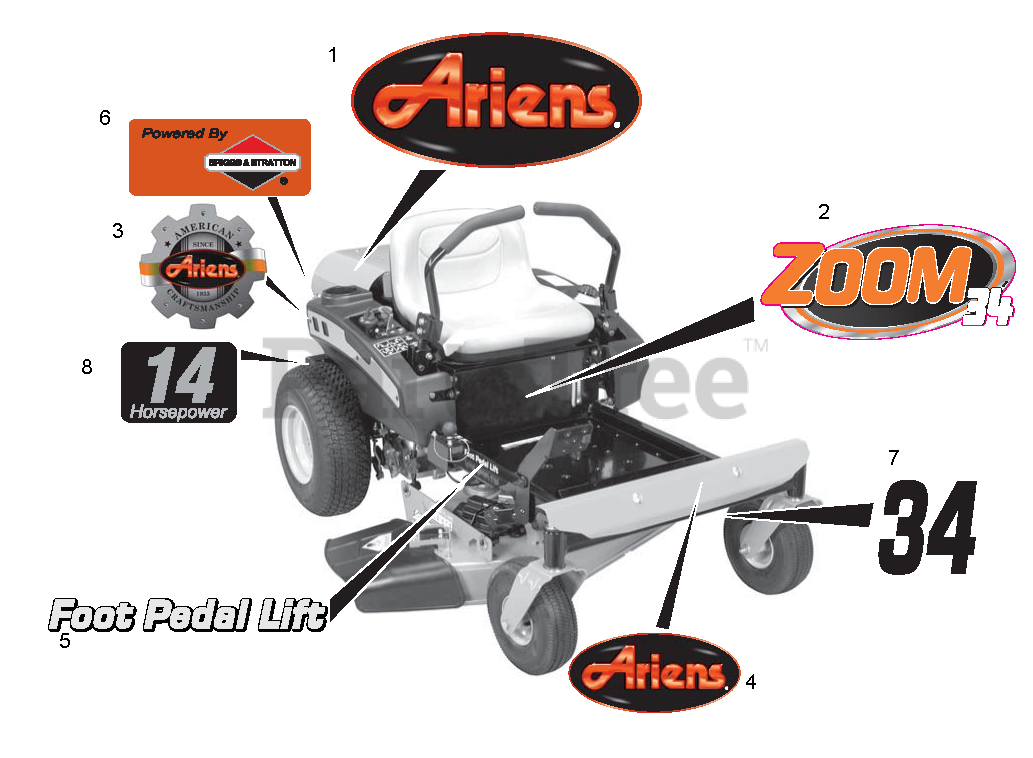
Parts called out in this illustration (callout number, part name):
1	DECAL, ARIENS JEWEL
2	DECAL, ZOOM 34
2	DECAL, ZOOM42
2	DECAL, ZOOM 50
3	Decal, Ariens Heritage, Large
4	DECAL. ARIENS DOMED JEWEL
5	DECAL, FOOT PEDAL LIFT
6	DECAL, POWERED BY B&S
6	DECAL, POWERED BY KOHLER
7	DECAL, DECK SIZE, 34"
8	DECAL, 14 HP
8	DECAL, 22 HP
